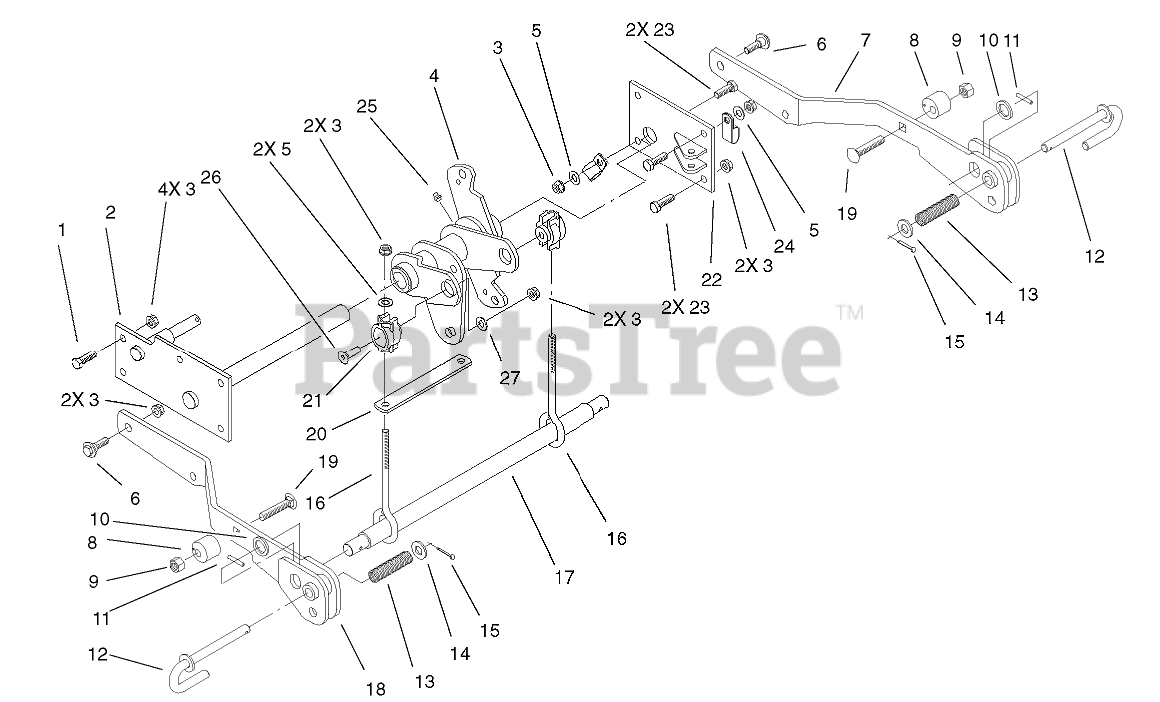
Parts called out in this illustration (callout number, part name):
1	SCREW-HH
2	SUPPORT-LIFT, DECK
3	NUT-LOCK, NI
4	BELLCRANK AND BUSHING ASM
5	WASHER-FLAT
6	BOLT-SHOULDER
7	ARM-LIFT, LH
8	STOP-LIFT, ADJ.
9	NUT-LOCK, NI
10	WASHER-FLAT
11	PIN-ROLL
12	PIN - J
13	SPRING-COMPRESSION
14	WASHER-FLAT
15	PIN-COTTER
16	ROD-LIFT
17	BAR-LIFT
18	Arm-Lift, RH
19	SCREW-CARR
20	SPACER-STRAP
21	SLEEVE-LIFT
22	SUPPORT-CYLINDER
23	SCREW-HH
24	CLAMP-TUBE
25	FITTING-GREASE
26	SCREW-HSFH
27	WASHER-FLAT
